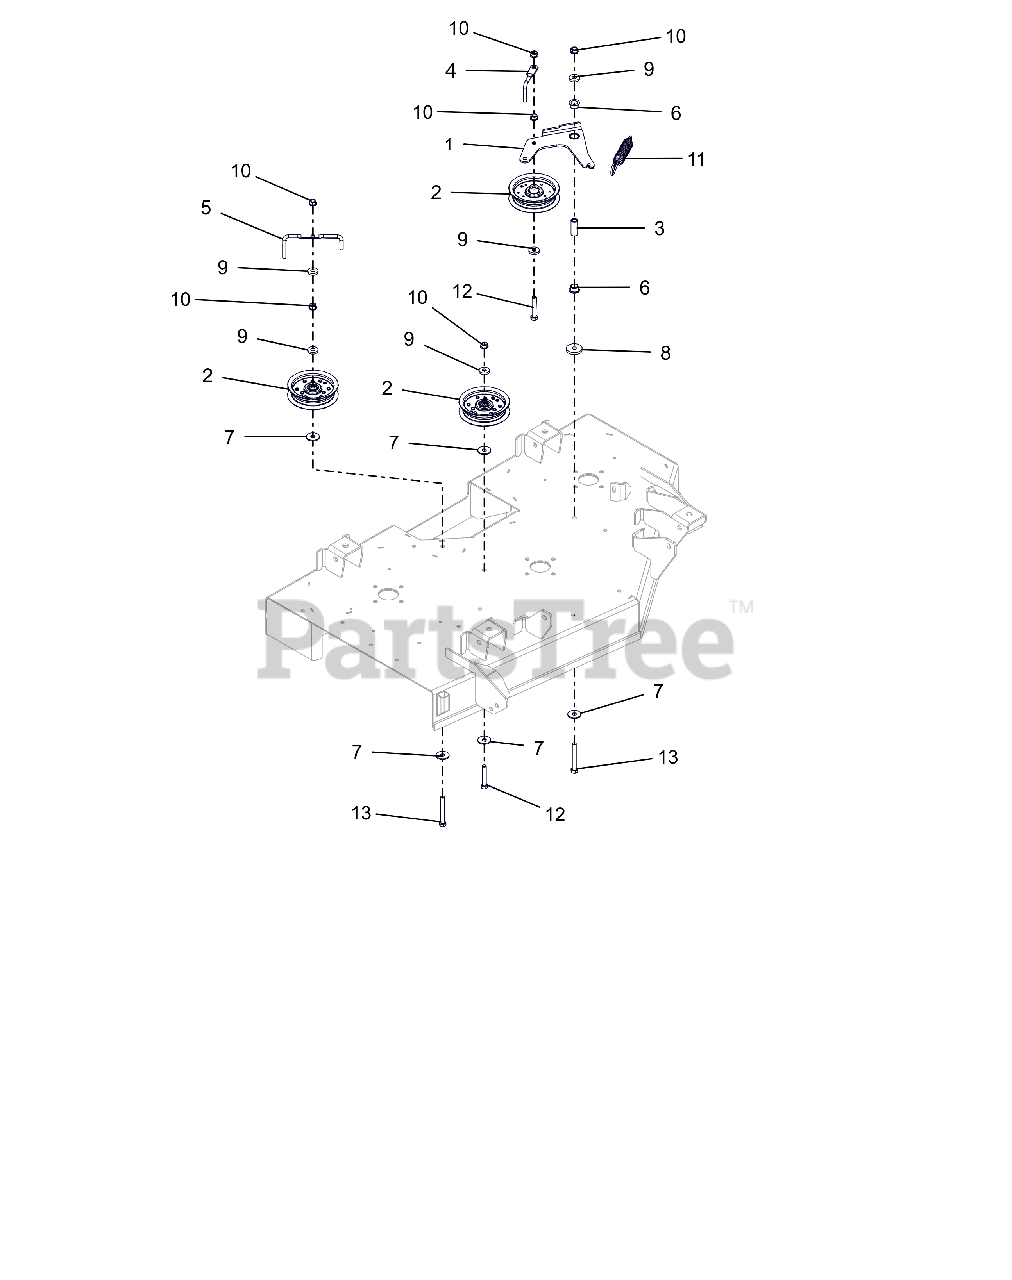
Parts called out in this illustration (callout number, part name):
1	WLDMT, IDLER ARM-42"
2	ASM, IDLER 4"
3	SPACER, .375IDX.625ODX1.66 PM
4	WIREFORM, BELT FINGER
5	WIREFORM, BELT FINGER
6	BSHG-FLG, .625X.750X.500X1.00
7	WSHR FL STL .406X1.25X.10ZC120
8	WSHR, FLT .406X1.50X.245 ZCC
9	WSHR, FLT .406X1.00X.188 ZCC
10	NUT-LK-TOP-FLG .38-16 ZC120
11	SG-TENS .135X.98X6.0 WLD 62
12	BLT,HEX .38-16X2.25 G5 ZCC
13	BLT, HEX .38-16X3.00F G5 ZCC
